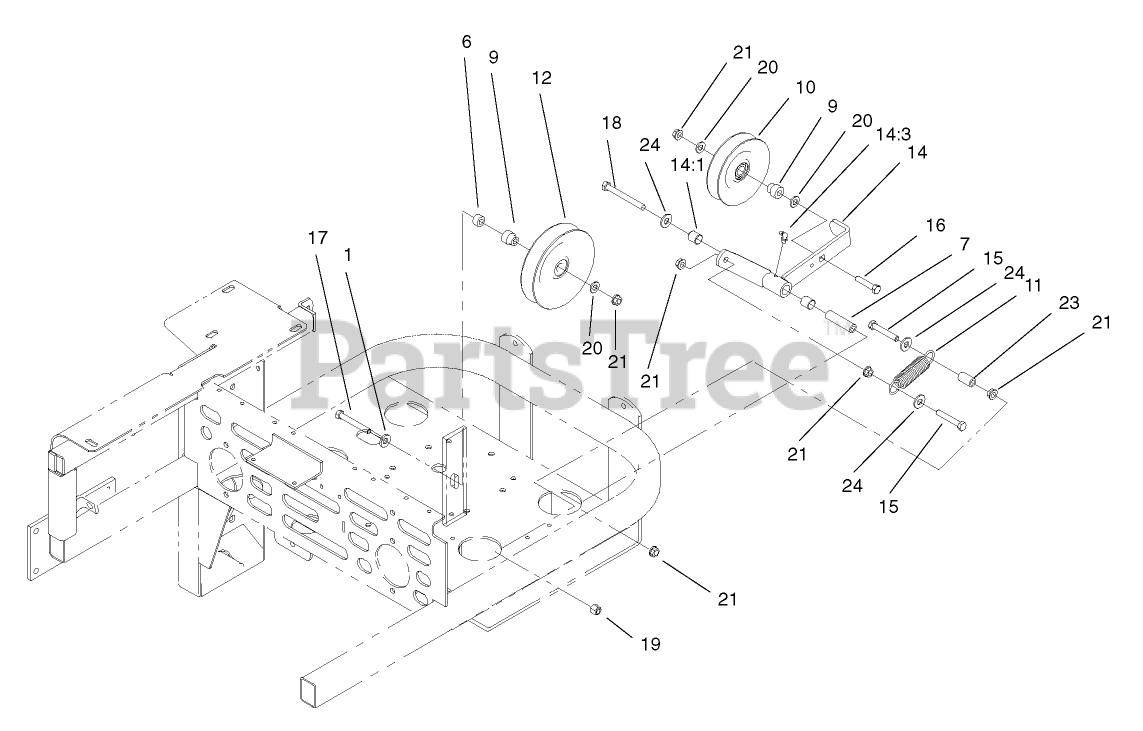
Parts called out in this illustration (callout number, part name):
1	WASHER-BELLEVILLE
6	SPACER
7	BUSHING-PIVOT, IDLER
9	BUSHING-IDLER
10	Idler
11	SPRING-EXTENSION
12	PULLEY-IDLER
14	IDLER ARM ASM
14:1	SLEEVE-BEARING
14:3	FITTING-GREASE, 90 DEG
15	SCREW-HH
16	SCREW-HH
17	SCREW-HH
18	SCREW-HH
19	NUT-LOCK, NI
20	WASHER-FLAT
21	NUT-HHF, WHIZ
23	SPACER
24	WASHER-FLAT
